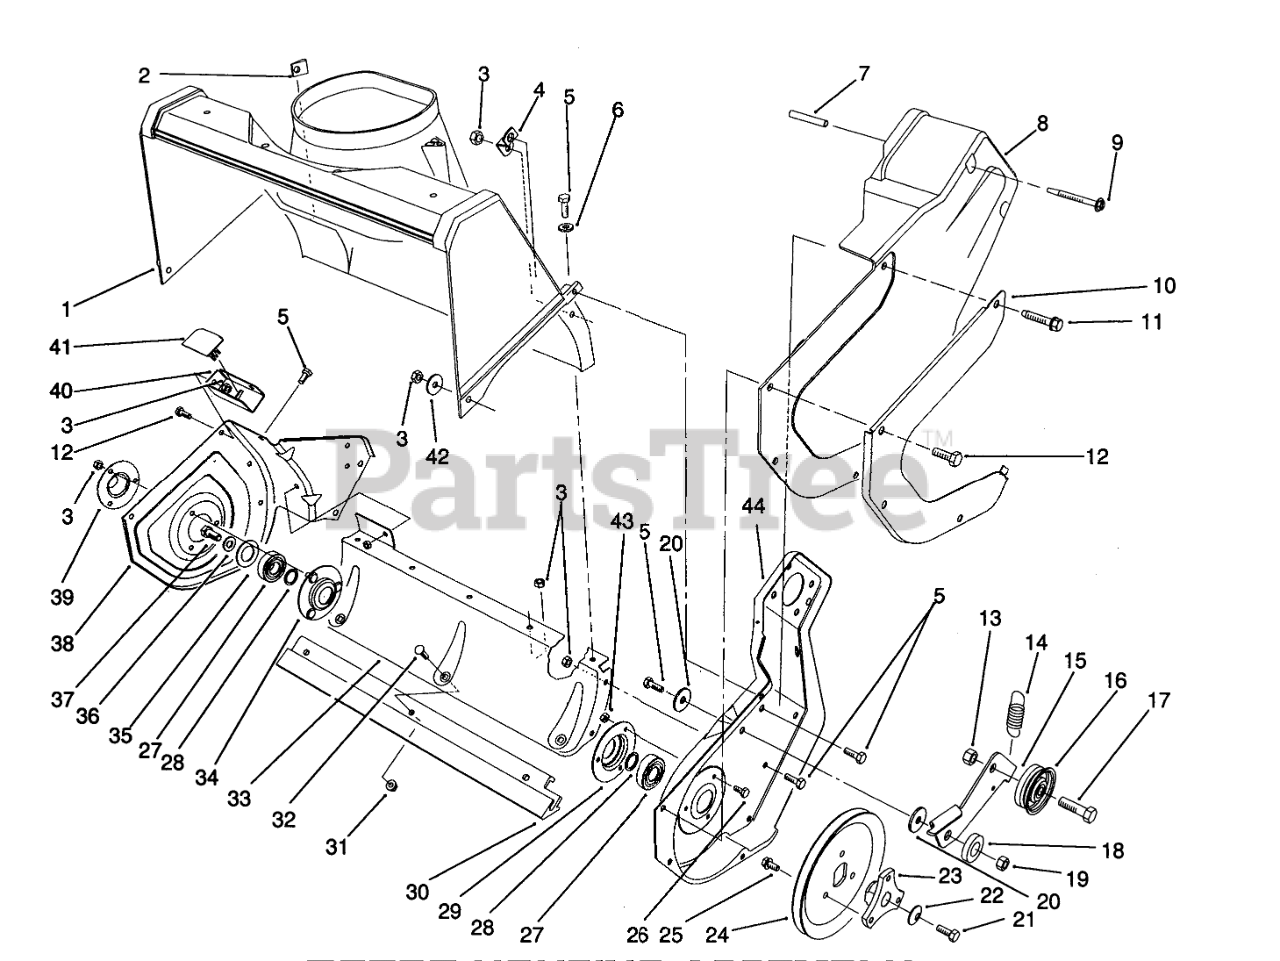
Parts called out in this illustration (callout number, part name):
1	HOUSING
2	SPEED NUT
3	NUT-LOCK, NI
4	BRACKET-HOUSING
5	SCREW-HH
6	WASHER-FLAT
7	TUBULAR SPACER
8	DRIVE COVER
9	SCREW-HWHTF
10	Guard-Drive Cover
11	SCREW-HWH, TAP
12	SCREW-HWH
13	NUT-LOCK, NI
14	SPRING-BRAKE
15	BRAKE ARM IDLER
16	PULLEY-IDLER
17	SCREW-HH
18	SPACER
19	NUT-LOCK, NI
20	WASHER-FLAT
21	SCREW-HH
22	WASHER-BELLEVILLE
23	HUB-MOUNTING, PULLEY
24	ROTOR PULLEY
25	SCREW
26	SCREW-SHH
27	BEARING-BALL
28	WASHER-THRUST
29	FLANGE-BEARING
30	SCRAPER
31	NUT-LOCK, HHF
32	SCREW-CARR
33	Housing-Lower
34	FLANGE-BEARING
35	WASHER-RUBBER
36	WASHER-FLAT
37	SCREW-HHF
38	Sideplate-R.H.
39	Trough
40	SIDEPLATE BRKT SUPT
41	BRACKET COVER
42	WASHER-FLAT
43	NUT-LOCK, NI
44	Sideplate L.H.
